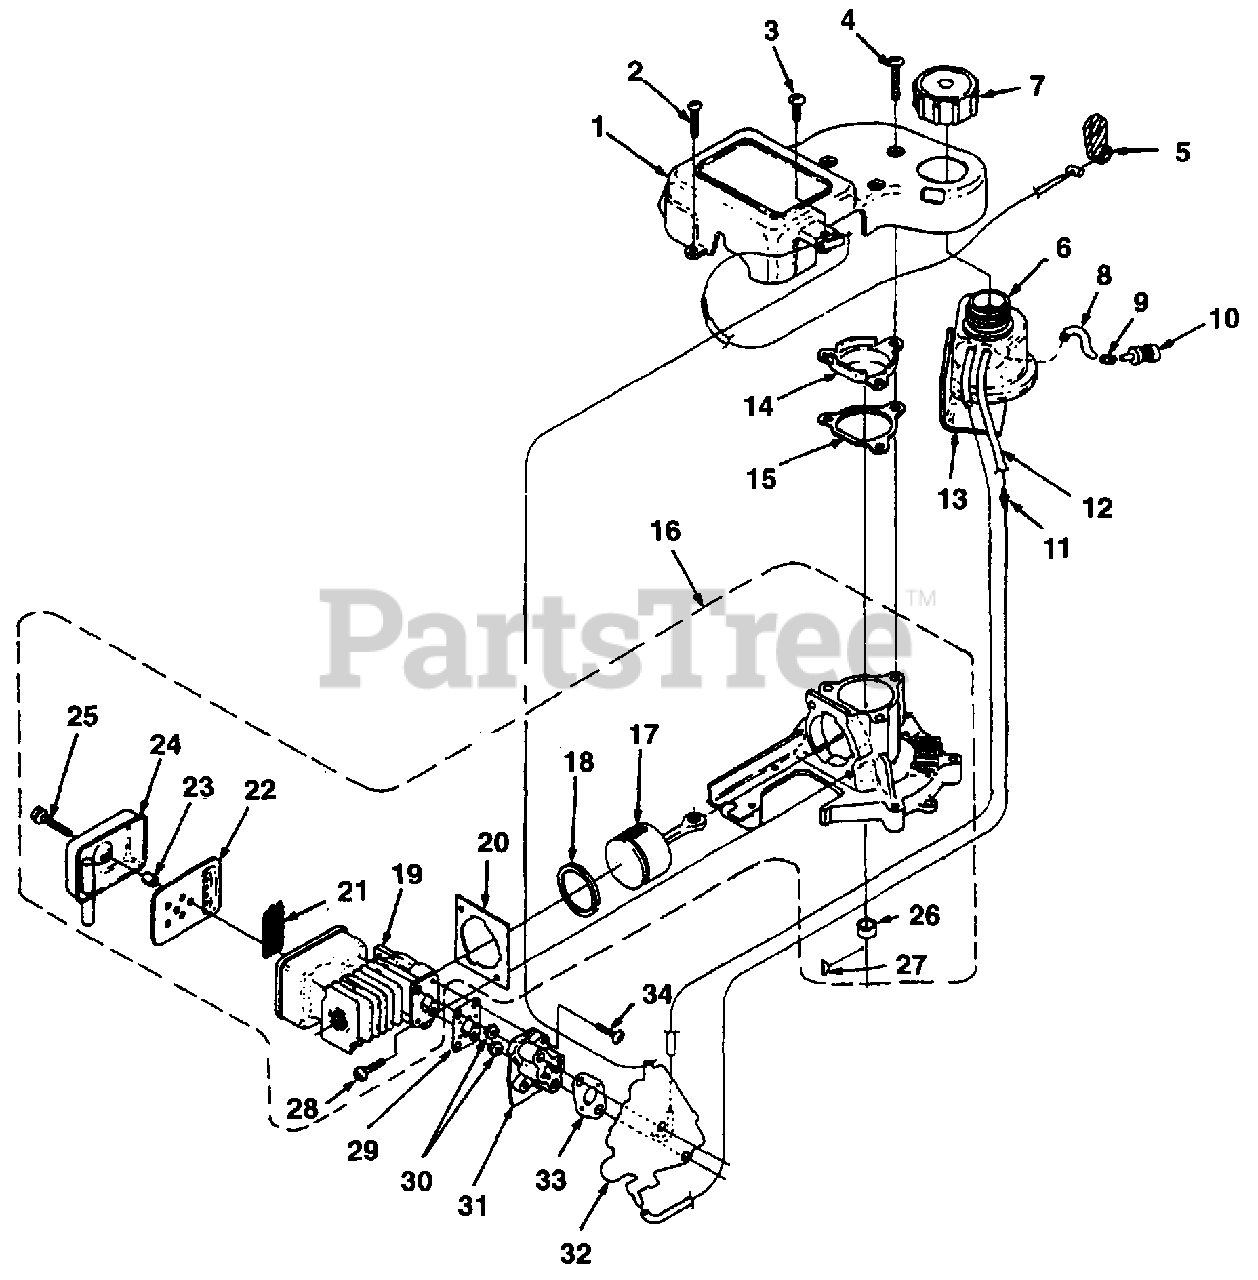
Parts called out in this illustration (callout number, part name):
1	COVER-Engine
2	SCREW-Thread Form. (#8 X 3/4")
3	SCREW-Thread Form. (#10 X 1/2")
4	SCREW-Thread Form. (10-24 X 3/4")
5	LEVER-Trigger
6	FUEL TANK ASSEMBLY
7	CAP-Fuel
8	TUBING-Rubber (5 1/2")
9	CLAMP-Wire
10	FILTER-Fuel
11	FITTING
12	TUBING-Rubber (6 1/4")
13	SPACER-Fuel Tank
14	CRANKCASE COVER
15	GASKET-Crankcase
16	SHORT BLOCK
17	PISTON & ROD
18	RING-Piston
19	CYLINDER & MUFFLER ASSEMBLY
20	GASKET-Cylinder
21	SCREEN-Spark Arrestor
22	BAFFLE Muffler
23	SPACER-Muffler
24	COVER-Muffler
25	SCREW-Thread Form. (8-32 X 1")
26	SPACER
27	KEY-Woodruff
28	SCREW-Machine (10-24 X 3/4")
29	GASKET-Heat Dam
30	NUT-Hex (10-24)
31	HEAT DAM
32	CARBURETOR KIT
33	GASKET-Carburetor
34	SCREW-Thread Form. (10-24 X 1")
